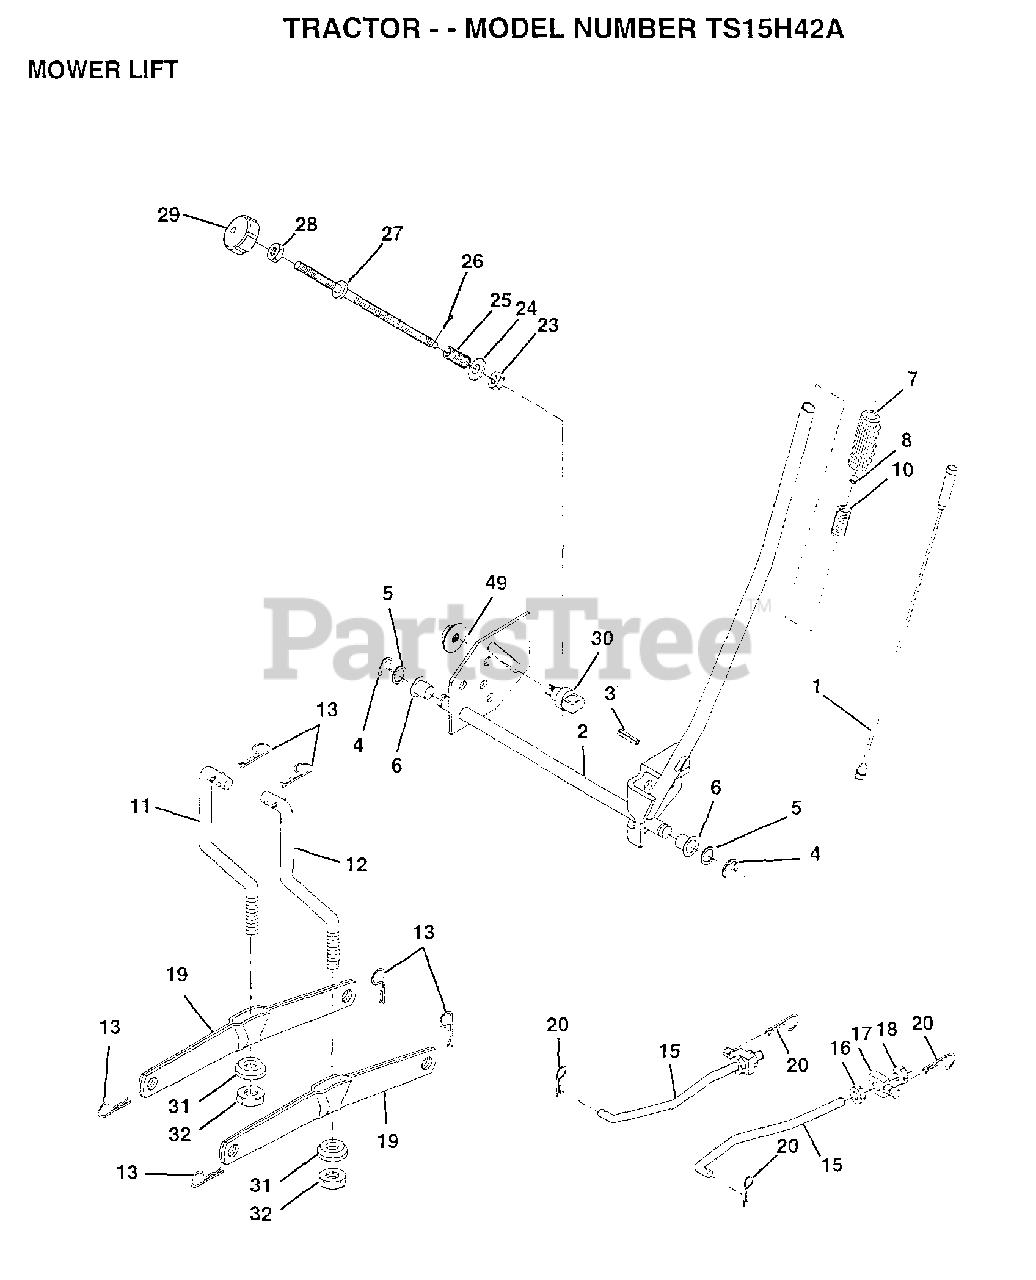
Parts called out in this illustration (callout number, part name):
1	WIRE.ASM.INNER
2	SHAFT.ASM.LIFT.RH
3	PIN GROOVE
5	WASHER
6	NYLON BEARING
7	GRIP
15	LINK.FRONT
16	NUT
17	TRUNION
18	NUT.LK.W/WSH.1/2.
19	ARM SUSP REAR
20	RETAINER.SPRING
23	NUT T
24	WASHER
25	SPRING.COMP.INF.H
27	ROD.ADJ.LIFT
28	NUT
29	KNOB INF 3/8-16
30	TRUNNION
31	BEARING PVT LH
32	NUT.CROWNLOCK.3/8
49	NUT.HXFLG.LOCK.
